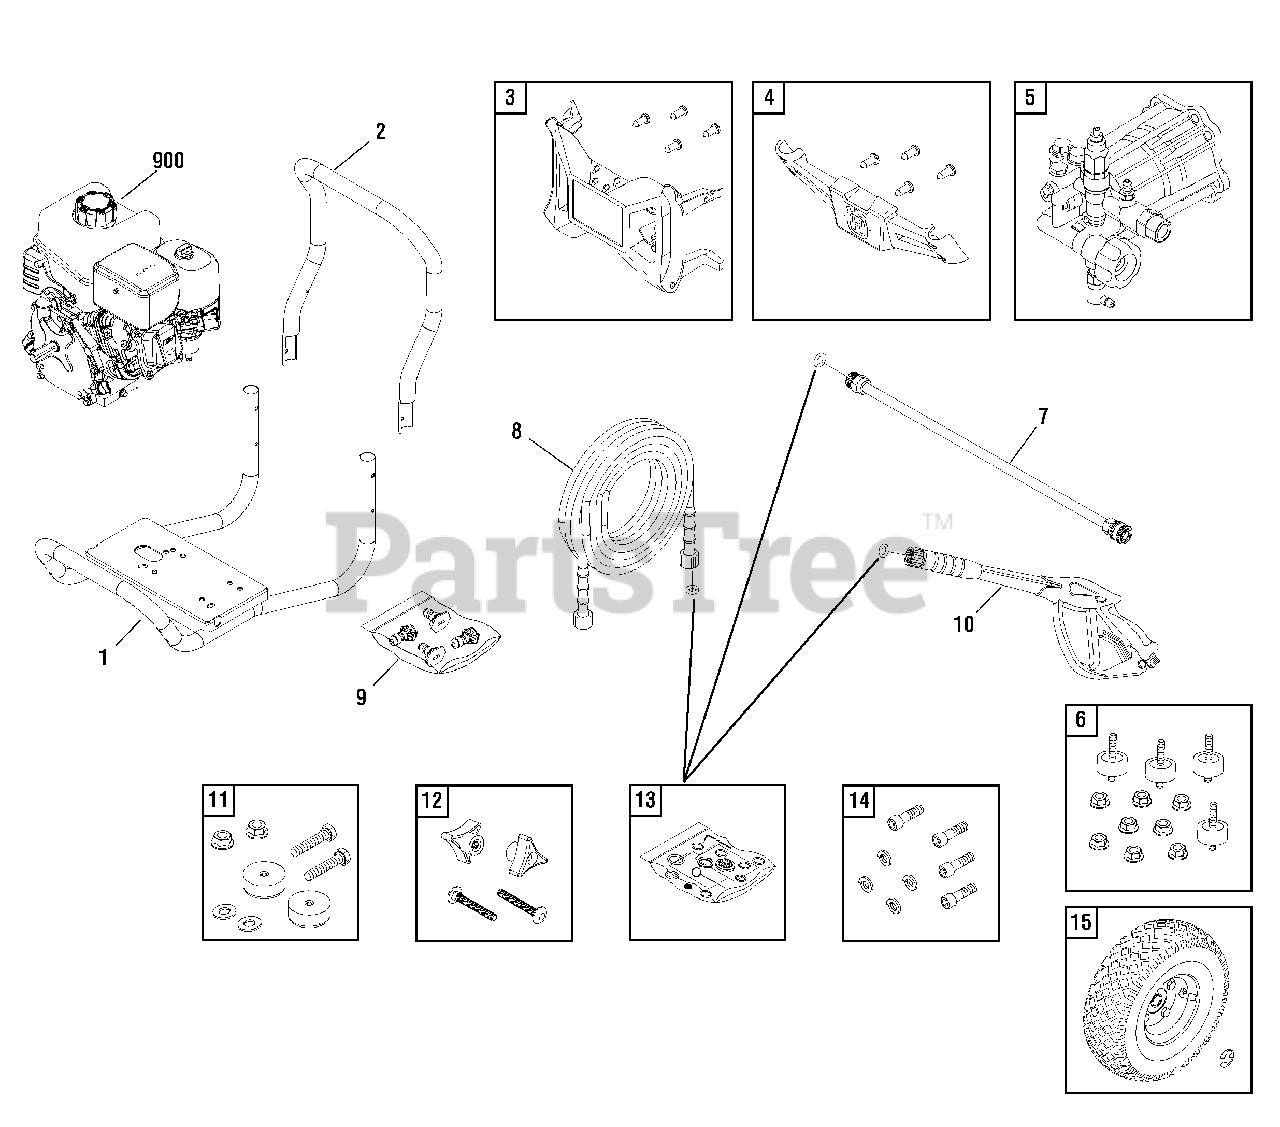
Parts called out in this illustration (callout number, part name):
6	KIT-VIBRATION MOUNT
9	KIT-QC NOZZLES
11	MOUNT-VIBRATION
12	KIT-HARDWARE HANDLE
14	KIT-HARDWARE PUMP MOUNTING
900	* ENGINE
